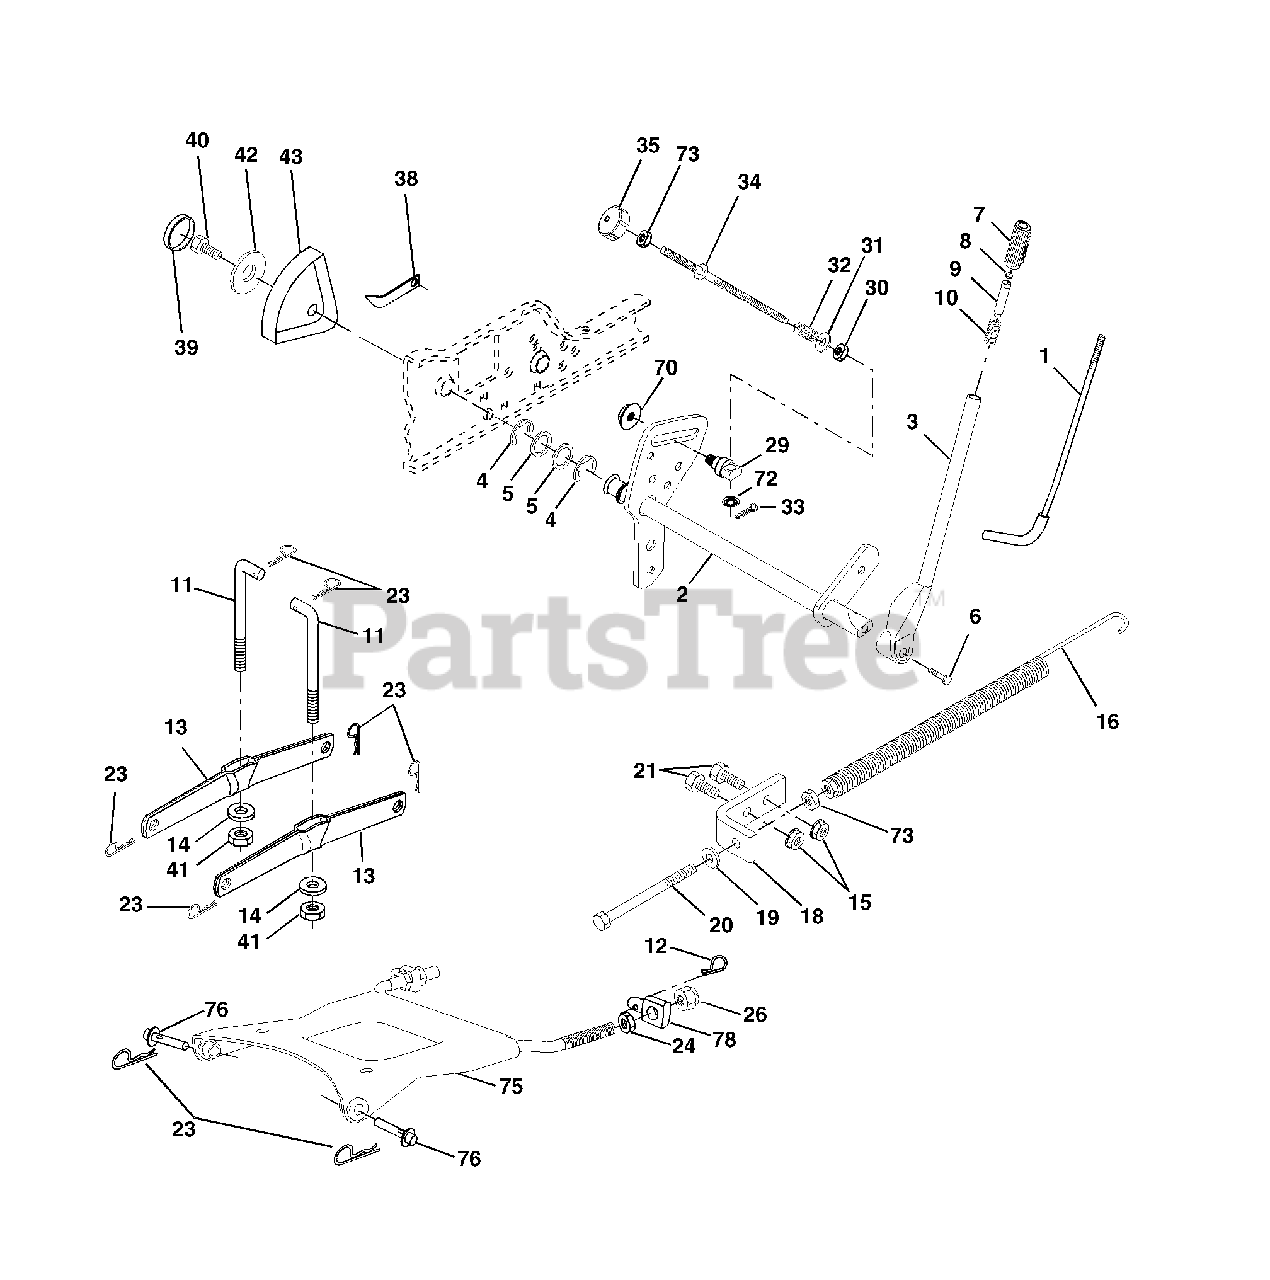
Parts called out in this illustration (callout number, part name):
1	Rod Asm., Lever
2	Shaft Asm., Lift Vgt
3	Lever Asm., Lift Rh
4	E-Ring Truarc #5133-87
5	Washer 29/32 x 1-1/4 x 16 Ga.
6	Bolt, Fin Hex 3/8-16 x 1-1/2
7	Grip, Handle
8	Button, Plunger
9	Plunger, Lever Lift
10	Spring 2-1/8"
11	Link Lift
12	Retainer, Spring
13	Arm, Suspension Vgt
15	Nut, Crownlock 3/8-16
16	Spring Asm., Assist Lift
18	Bracket, Spring Assist
19	Washer 13/32 x 13/16 x 16 Ga.
20	Bolt, Adjust Spring Assist
21	Bolt, Fin Hex 3/8-16 x 1
23	Retainer, Spring
24	Nut, Jam Hex 1/2-13 Unc
26	Nut, Lock W/Wsh 1/2-13 Unc
29	Trunnion Infin Height
30	Nut, Special
31	Washer 13/32 x 5/8 x 16 Ga.
32	Spring, Compression Inf Hgt
33	Pin, Cotter 3/32 x 1/2
34	Rod, Adj Lift
35	Knob, Inf 3/8-16 Unc
38	Pointer Height Indicator
39	Plug, Hole Blk. 1.485/1.515 Dia.
40	Screw 5/16-18 x 1
41	Nut, Crownlock 3/8-24
42	Washer 11/32 x 1-1/2 x 10 Ga.
43	Scale, Indicator Height
70	Nut Hex Flange Lock
72	Nut Push Phos & Oil
73	Nut Hex Jam 3/8-16
75	Plate Asm. Susp front
76	Pin Flange
